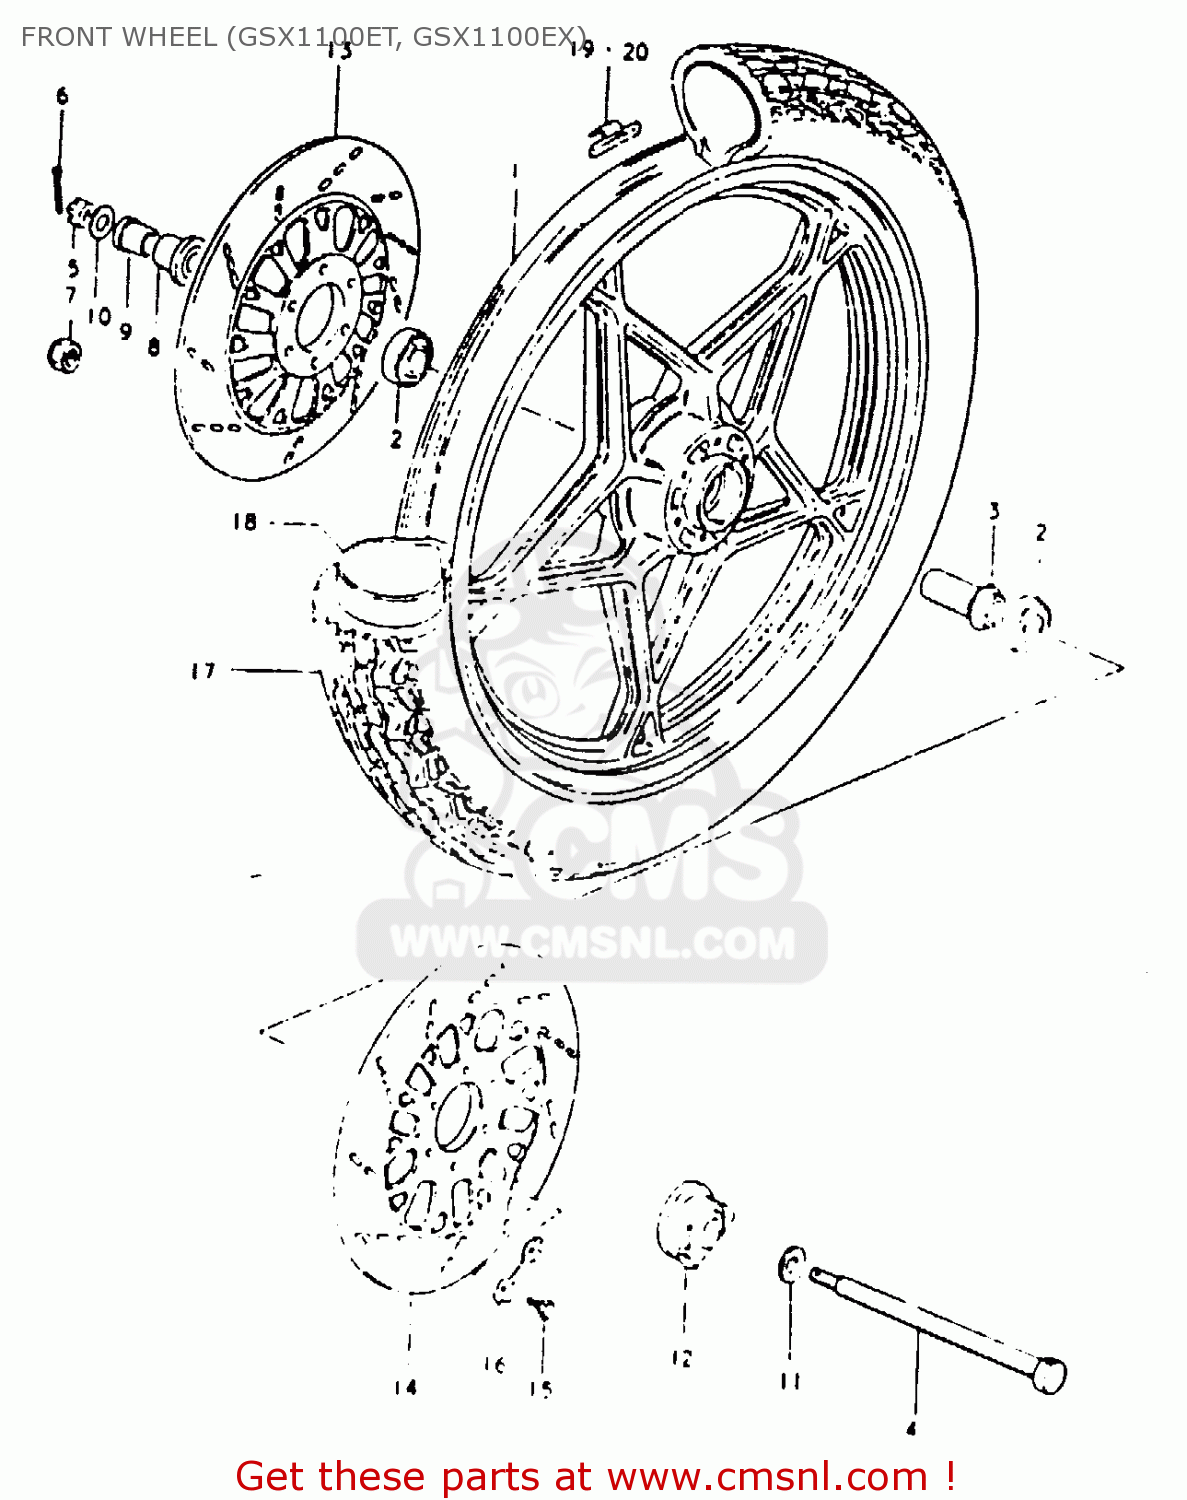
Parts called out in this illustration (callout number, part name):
1	WHEEL, FRONT
2	BEARING
3	SPACER,FR HUB BEARING
4	AXLE,FR
5	NUT 12MM
6	COTTER PIN
8	SPACER,FR AXLE,R
9	SPACER
10	WASHER
11	WASHER(15.5X26X2.3)
12	BOX ASSY,SPEEDOMETER GEAR
13	DISC,FR BRAKE,R
14	DISC,FR BRAKE,L
15	BOLT(8X25)
16	WASHER
17	TIRE (3.50V19)
18	TUBE,INNER
19	BALANCER,WHEEL
20	BALANCER,WHEEL
